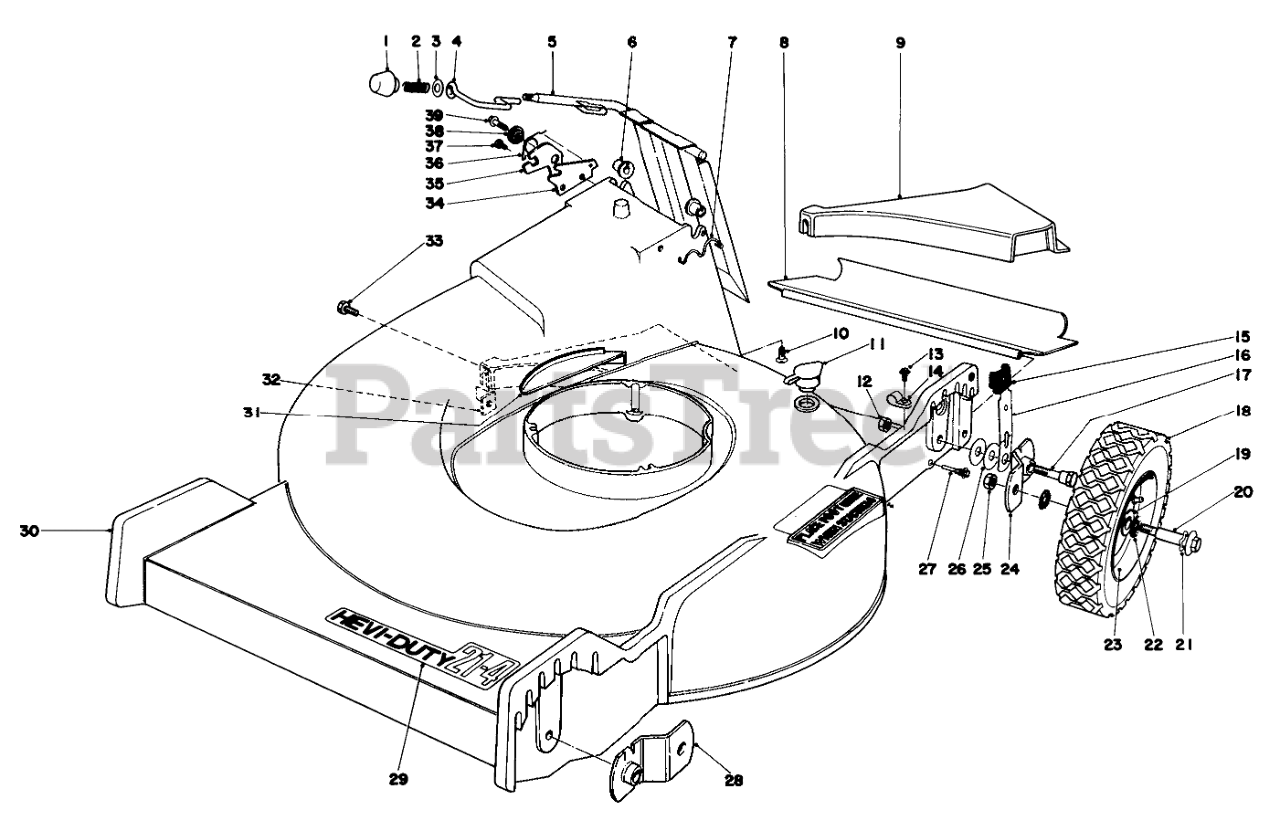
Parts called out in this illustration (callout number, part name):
2	COMPRESSION SPRING
3	WASHER
4	DOOR LATCH
5	Door Handle
6	BUSHING-NYLON
7	Door Retainer
8	REAR SAFETY SHIELD
9	REAR INSERT
10	SCREW-HH
11	WASHOUT PLUG
12	Nut
13	SCREW
14	CABLE CLAMP
15	KNOB-ARM
16	SPRING ARM ASM
17	PIVOT SCREW
19	BEARING-BALL
21	SPRING WASHER
22	FELT WASHER
23	Wheel & Tire Assembly (Incl. Ref. #18 & 19)
24	PIVOT ARM ASM A
25	Nut
26	Washer
27	SAFTEY SHIELD SCREW
28	PIVOT ARM ASM B
29	Decal-21-4 Hevi-Duty
30	Housing
31	HOUSING CAP
32	SPECIAL NUT
33	SCREW THD 1/4 20 5/8
34	DOOR LATCH PLATE
35	Latch Safety
36	TORSION SPRING
37	SCREW-HWH
38	Latch Spacer
39	Screw
